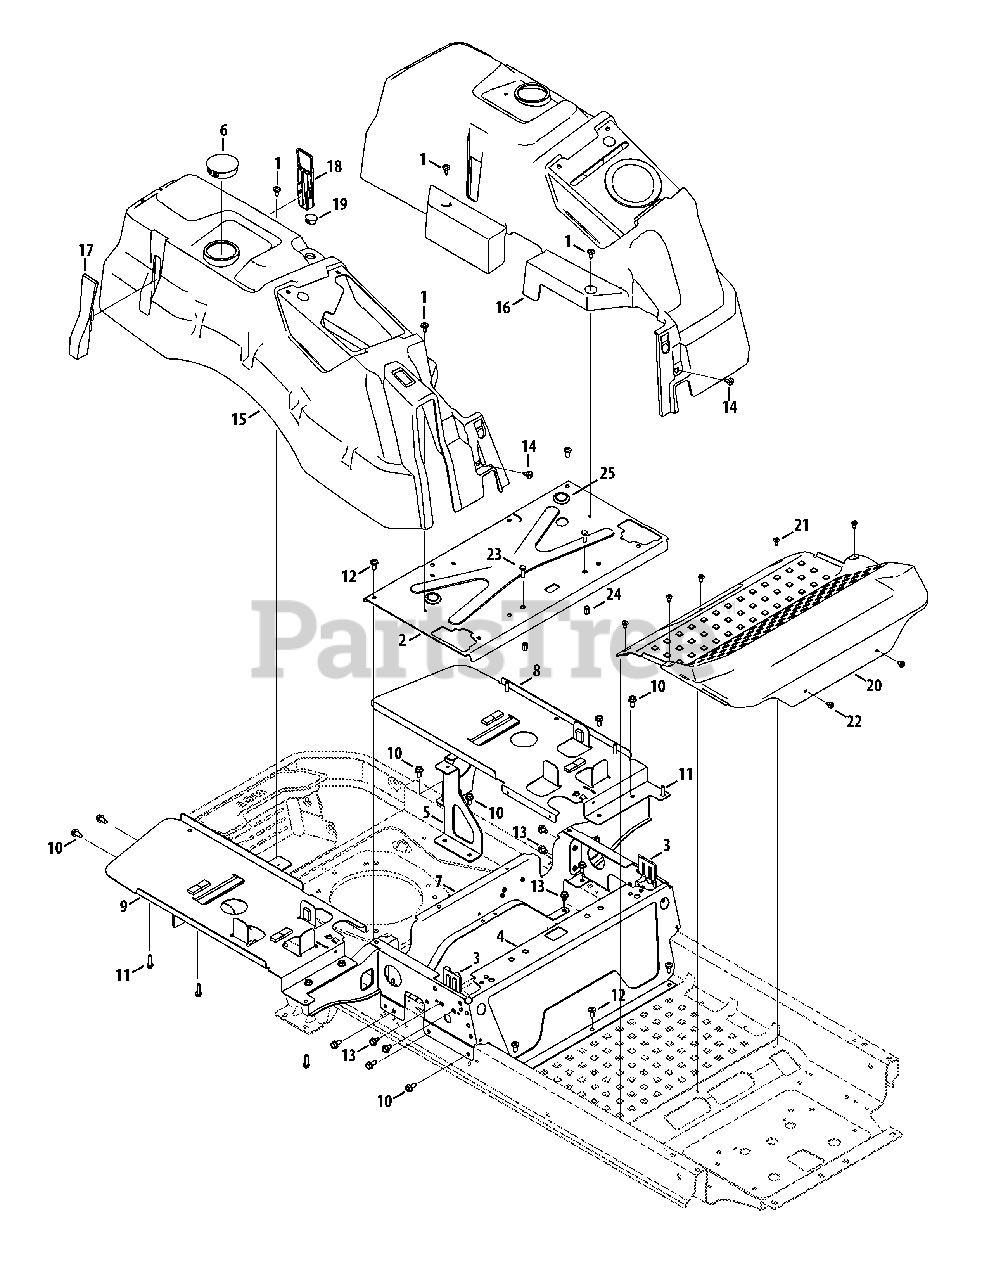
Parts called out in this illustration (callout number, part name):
1	Shoulder Screw, .368 x .115, M6-1
2	Seatbox Plate
3	Lapbar Brace Bracket
4	Seat Frame
5	Rear Support Bracket, LH
5	Rear Support Bracket, RH
6	Plug, 2.50 Dia.
7	Rear Seatbox Brace
8	Tank Support Plate, LH
9	Tank Support Plate, RH
10	Hex Washer Screw, 5/16-18 x .750
11	Hex Washer Screw, 5/16-14 x 1.00
12	Self Tapping Screw, 5/16-18 x .750
13	Hex Washer Screw, 5/16-18 x .50
14	Shoulder Screw, 1/4-20
15	RH Console
16	LH Console
17	Outer Pod Plug
18	Inner Pod Plug
19	Plug, .875 Dia.
20	Floor Board
21	Screw, 1/4-20 x .50, Black
22	Screw, 5/16-18, .750
23	Hex Cap Screw, 5/16-18 x 1.00
24	Nut, 5/16-18
25	Button Plug
